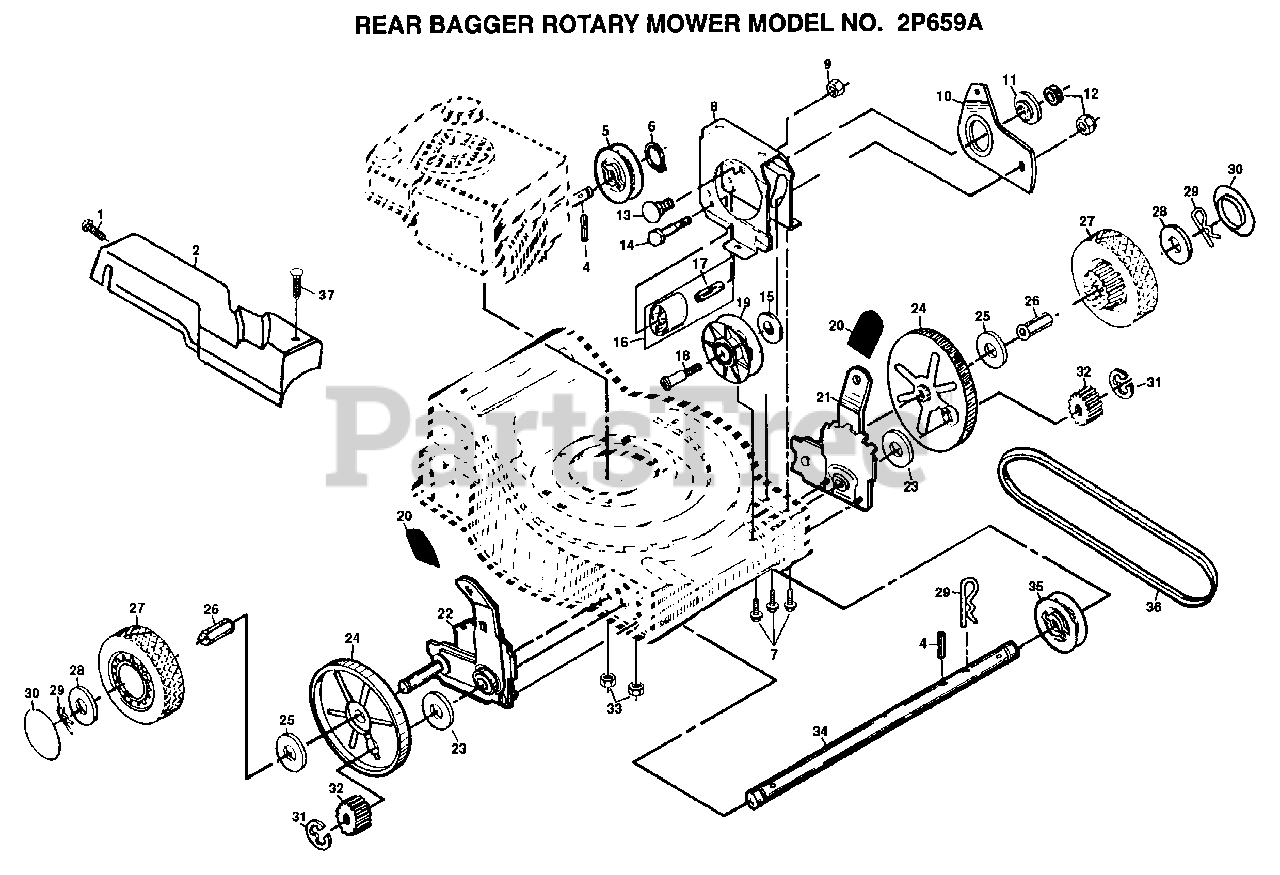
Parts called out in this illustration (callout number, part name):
1	SCREW HXHD 10-24
2	COVER.DRV.B&S.20
4	DRIVE PAWL
6	RETAINING RING ST
7	SCREW
8	"CLUTCH,FRAME"
9	LOCKNUT
11	SPACER PM
12	LOCKNUT
13	CARRIAGE BOLT
14	BOLT 1/4-20-1 1/2
15	SPACER PM
17	IDLER SPACER
18	SHOULDER BOLT
19	IDLER PULLEY
20	KNOB PM
23	WASHER PM
24	DUST SHROUD PM
25	WASHER FLUT
26	BUSHING.HEX
27	WHEEL &TIRE ASSY
28	WASHER
29	RETAINER CLIP PM
30	HUB CAP
31	E-RING.7/16.RE.
32	PINION.GEAR
34	SHAFT.DRIVE.17.81
35	DRIVE PULLEY PM
37	FASTNER PUSH DRCV
